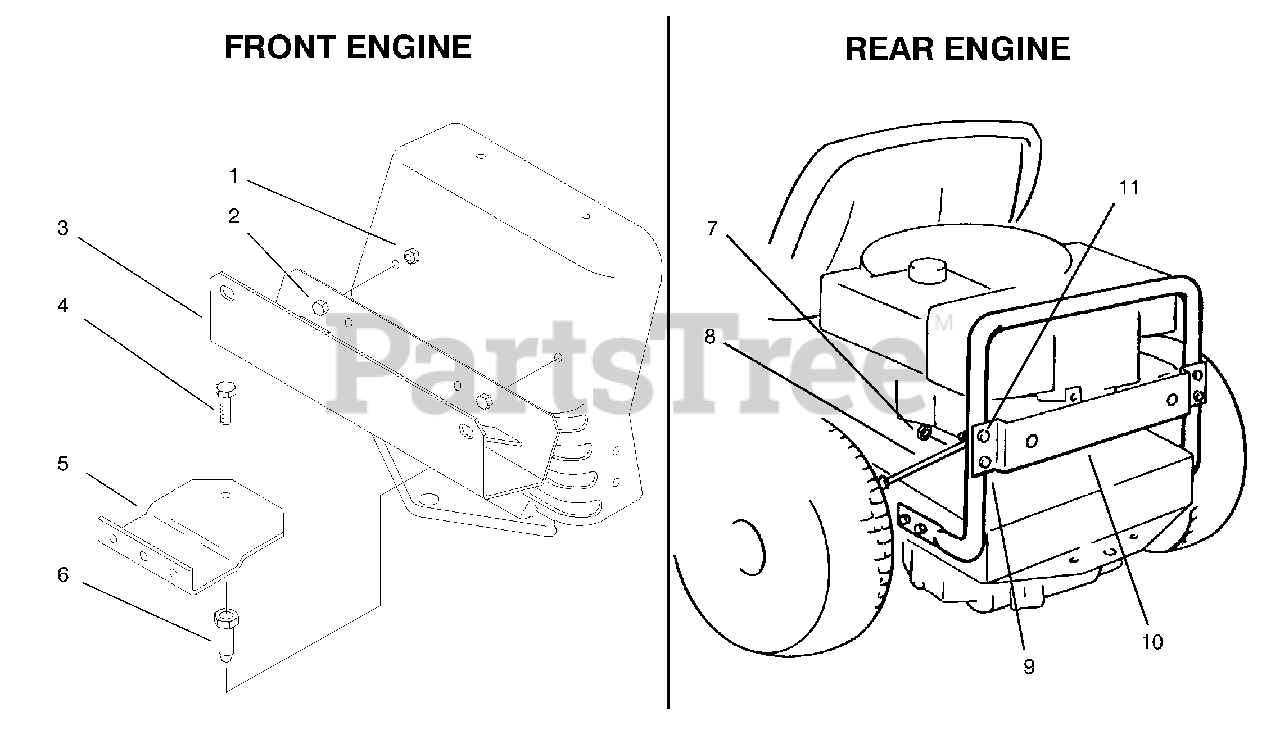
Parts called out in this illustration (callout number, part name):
2	Screw-Cap
3	Bracket-Channel
4	Screw-Cap
5	Bracket-Bagger Mounting
6	Pin-Mounting, Lower
8	Brace-Bagging
9	Screw-Cap
10	Plate-Bagging Kit
11	Screw-Cap
